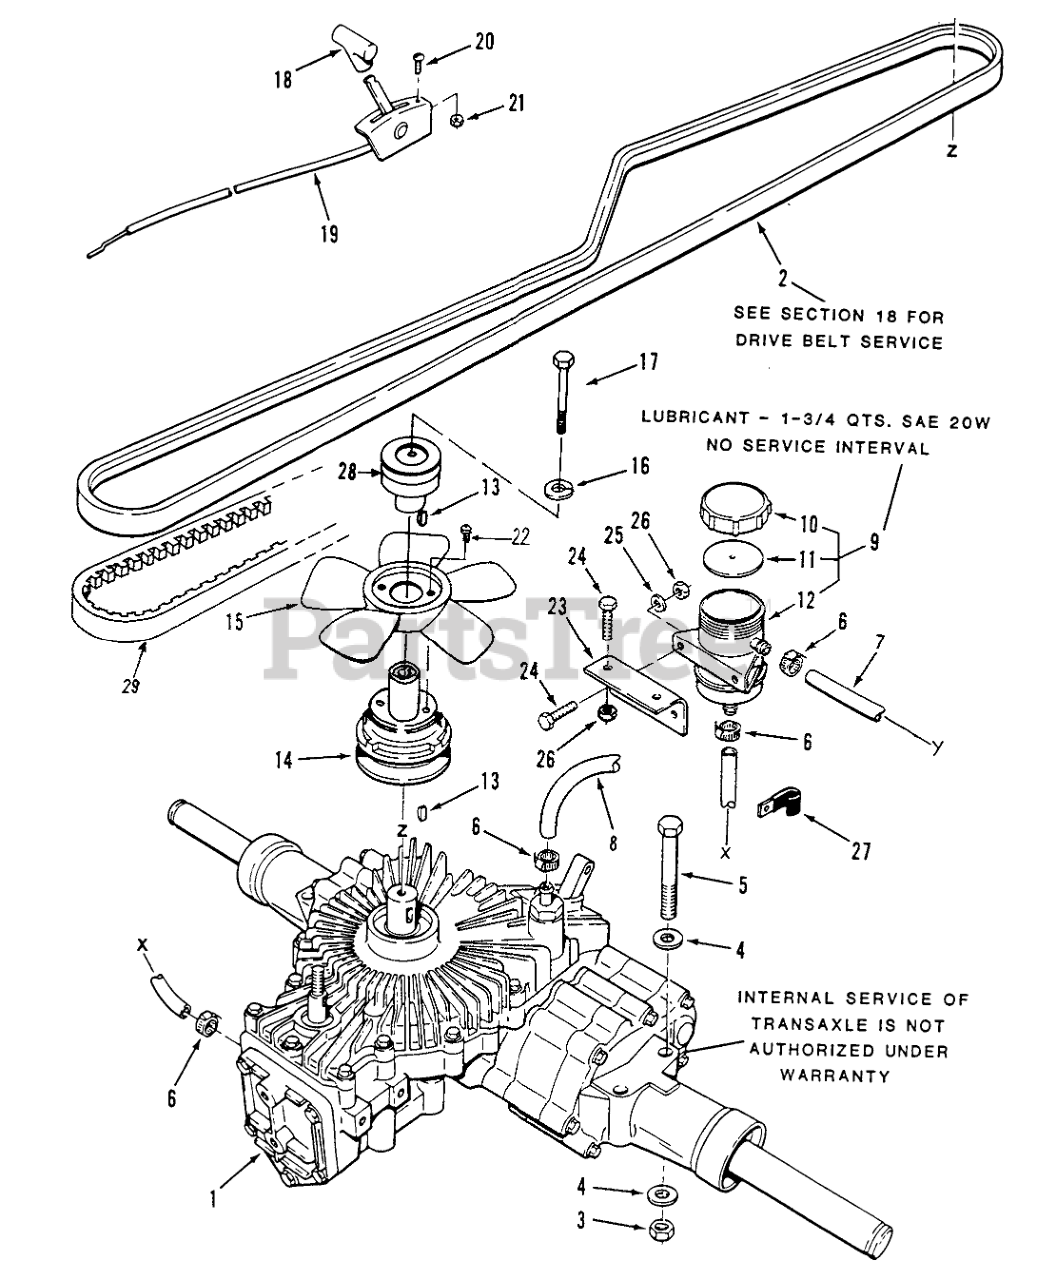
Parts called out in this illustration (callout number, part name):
2	BELT V
3	Nut
4	WASHER 5/16 SAE
5	Pin-Cotter
6	CLAMP
7	S/A 9" OF 114702
8	S/A 27" OF 114702
9	Hydro Reservoir Complete (includes items 10, 11 & 12)
10	Cover
11	COVER GASKET
12	RESERVOIR
13	HARD HI PRO KEY
14	PULLEY-DRIVER
15	BLADE-FAN
16	Washer
18	KNOB-CONTROL
19	Push Valve Cable
20	Screw
21	Nut
22	Screw-Flat Hd.
23	BRKT-RESERVOIR MT R
24	Bolt
26	Nut
27	CLIP
28	PULLEY-DRIVER
29	SERV ASSY-HOOD & PKG
